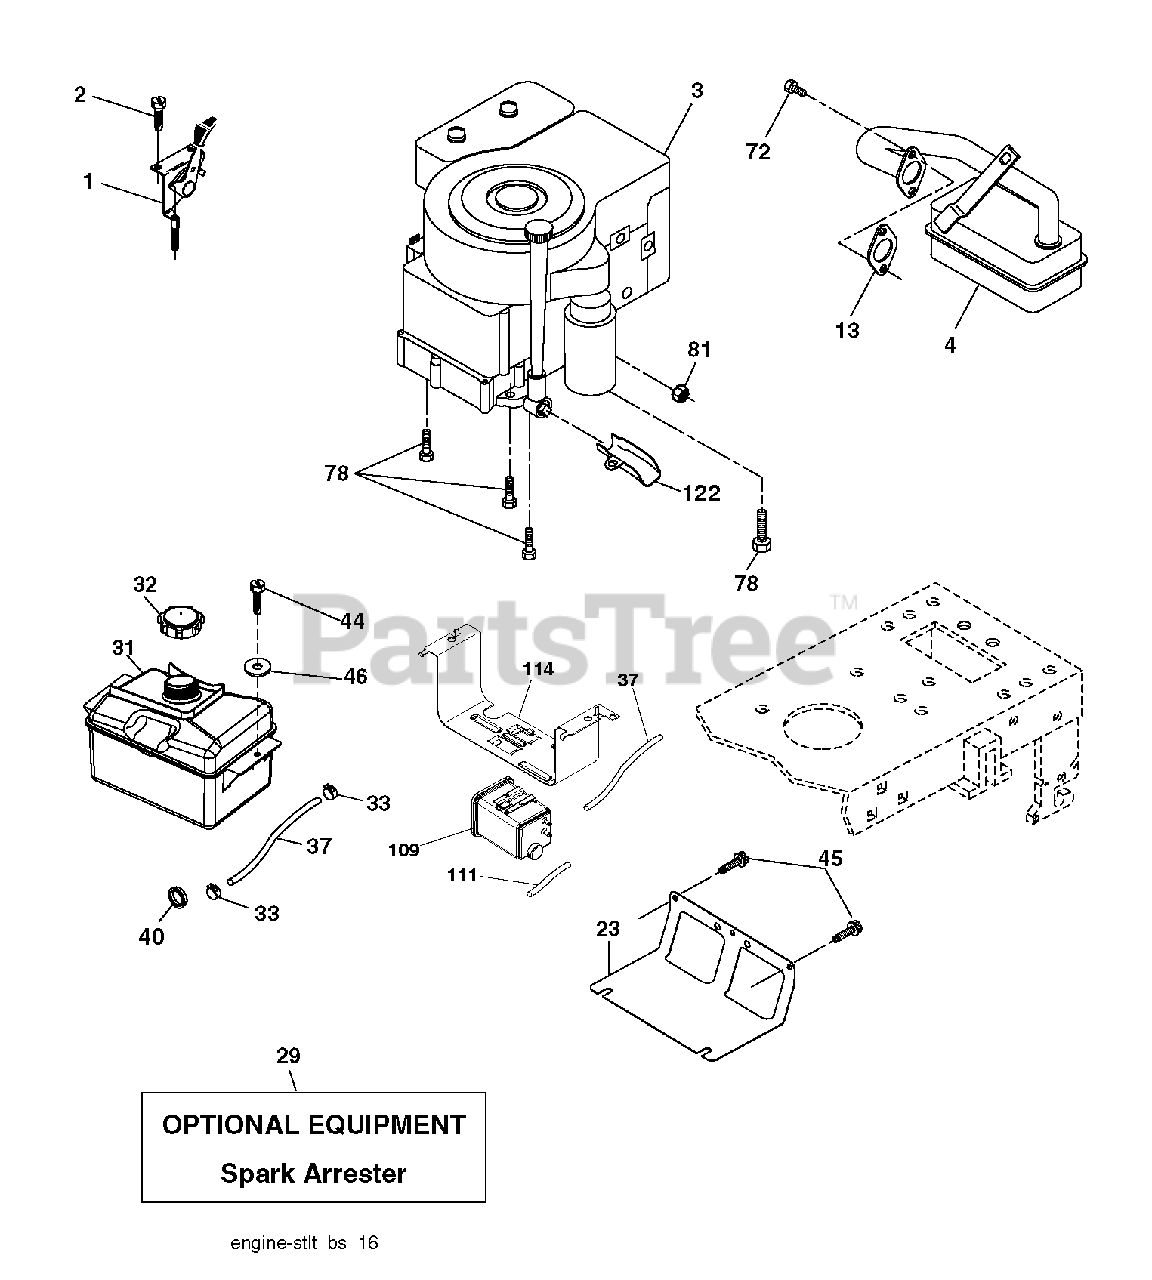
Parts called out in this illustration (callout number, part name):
1	CONTROL.THROTTLE/CHOKE.BLACK
2	SCREW
3	Poulan TBD
4	MUFFLER.LT.BRIGGS.14HP.IC/OHV
23	SHIELD.BROWNING.DBR.GUARD
29	KIT.SPARK ARRESTOR(392390 B&S)
31	TANK ASM.FRONT.CARB
32	CAP ASM.FUEL.2.25"FRT.CARB
33	HOSE CLAMP
37	LINE.FUEL.20"FRONT.EMI
40	GROMMET T
44	SCREW HEXWSHR 1/4-20X3/4
45	SCREW, 3/8-16X3/4
72	SCREW.SOCKET HD.5/16-1
78	SCREW.3/8-16
81	NUT
109	CANNISTER, CARBON
111	RP PURGE LINE
122	EXTENSION DRAIN OIL
